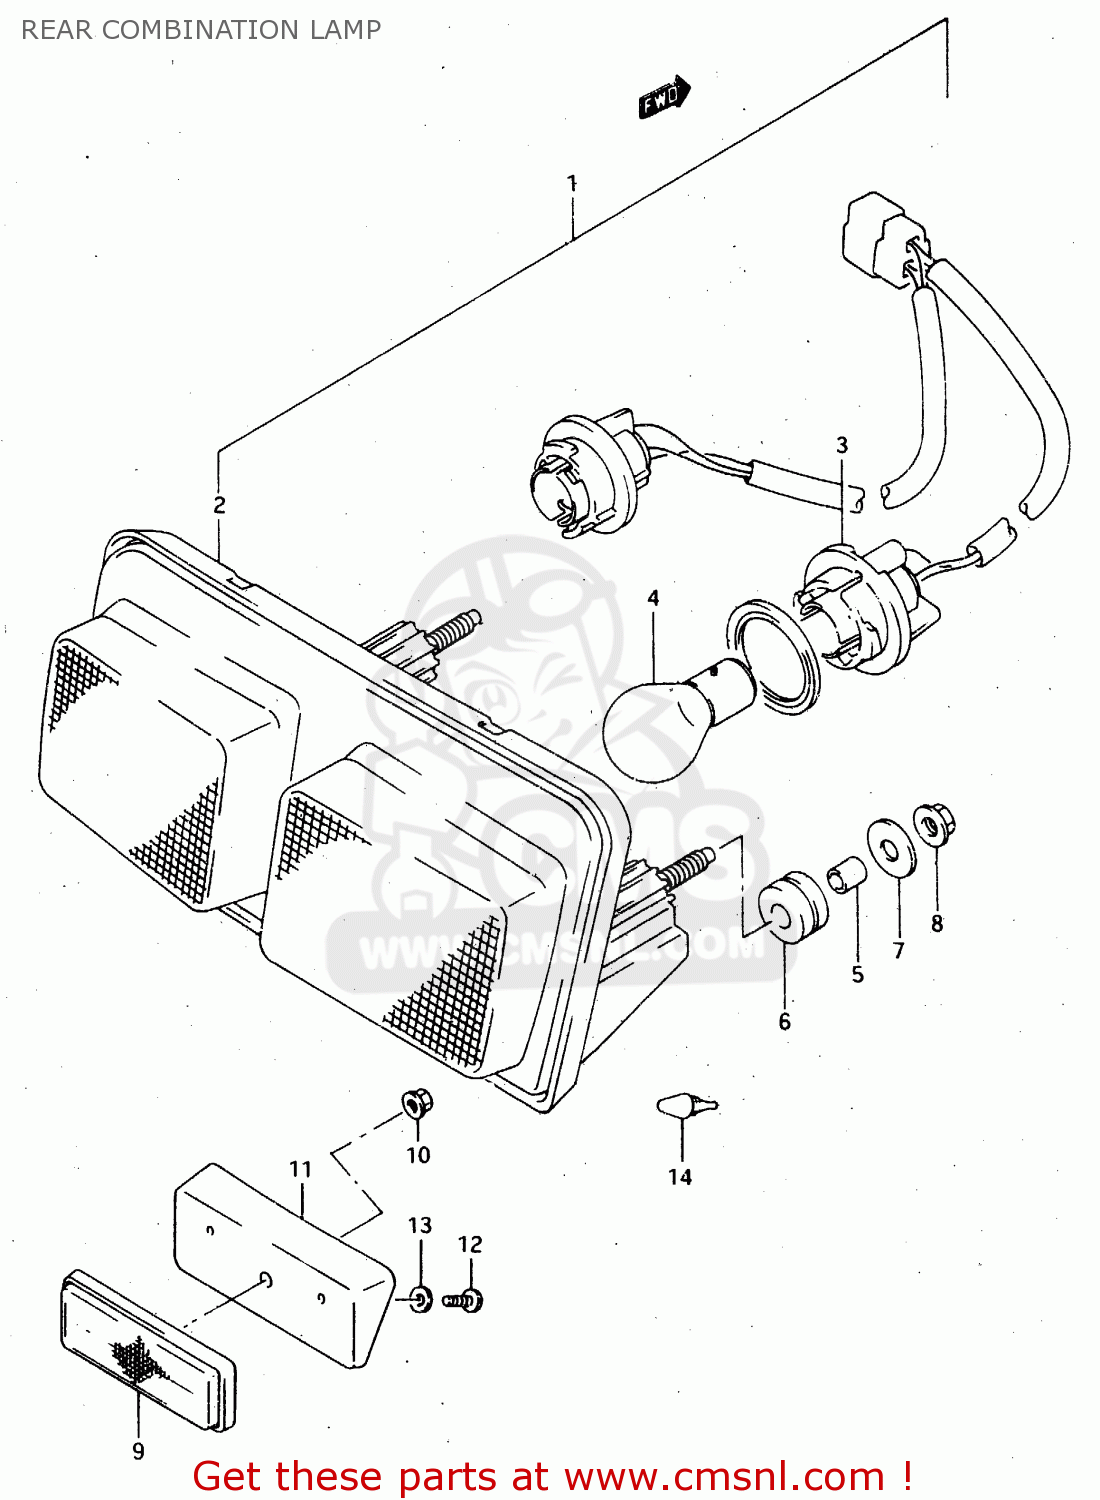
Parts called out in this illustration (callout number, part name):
1	LAMP ASSY,RR C
2	LAMP UNIT
3	SOCKET,RR COMB
4	BULB(12V21/5W)
5	SPACER (6.1X8X9.5)
6	CUSHION
7	WASHER(6.5X18X1)
8	NUT
9	REFLECTOR ASSY,RR
10	NUT
11	SPACER,RR RR
12	SCREW
13	WASHER
14	CUSHION
